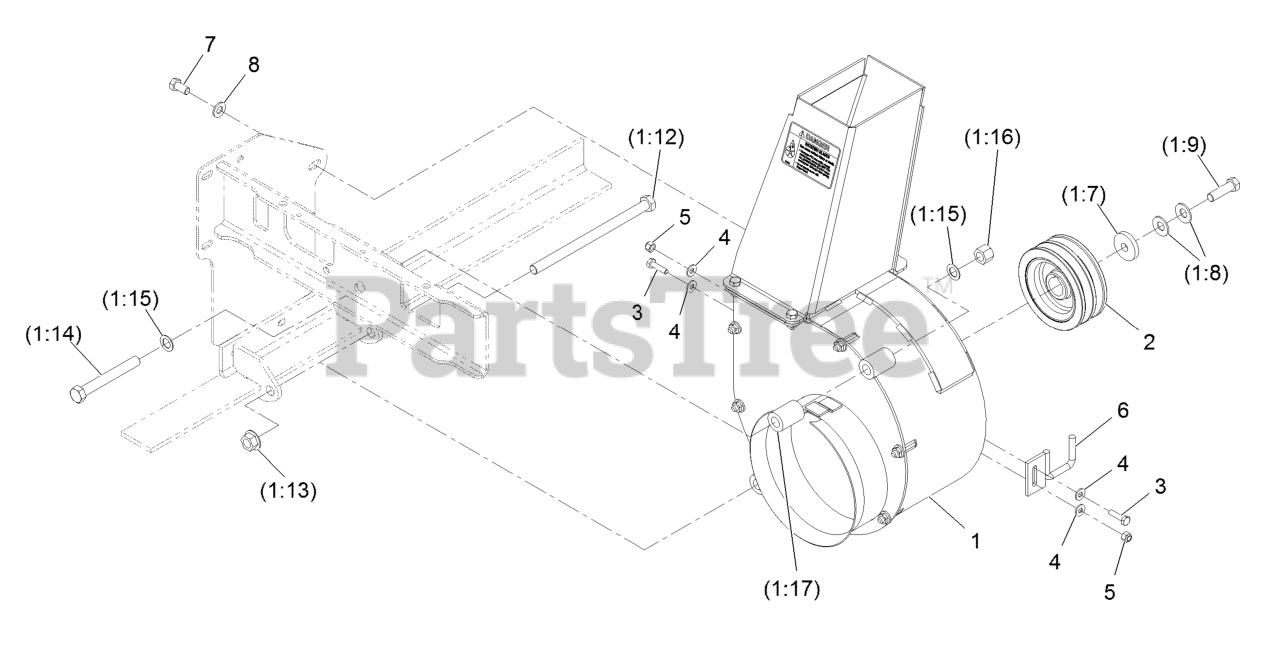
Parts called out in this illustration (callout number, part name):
1	BLOWER ASM
3	SCREW-HH
4	WASHER-FLAT
5	NUT-LOCK, NI
7	SCREW-HH
8	WASHER-FLAT
